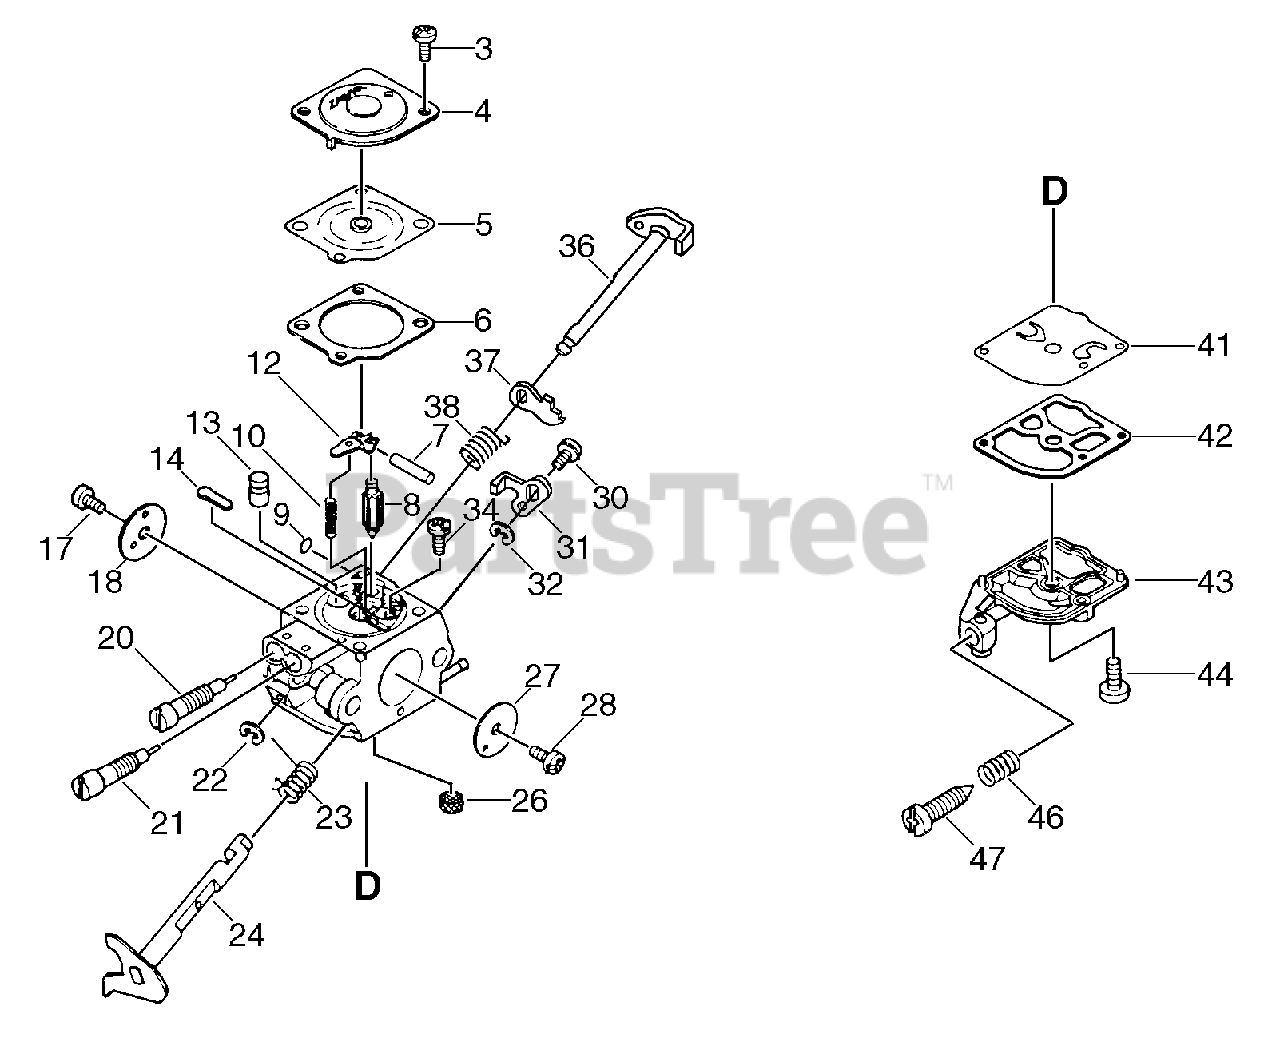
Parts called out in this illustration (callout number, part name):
4	COVER, METERING
5	DIAPHRAGM, METERING
6	GASKET, DIAPHRAGM
7	PIN, METERING LEVER
8	VALVE, INLET NEEDLE
9	PLUG, WELCH
12	LEVER, METERING
13	NOZZLE CHECK VALVE
14	PLUG, WELCH
18	VALVE, CHOKE
20	NEEDLE - HIGH SPEED
21	NEEDLE - LOW SPEED
22	RING, RETAINING
23	SPRING, THROTTLE RETURN
24	SHAFT, THROTTLE
26	STRAINER
27	VALVE, THROTTLE
31	LEVER, THROTTLE
32	RING, RETAINING
34	SCREW, METERING LEVER PIN
36	SHAFT, CHOKE
37	LEVER, CHOKE
38	SPRING, CHOKE RETURN
41	DIAPHRAGM, PUMP
42	GASKET, PUMP
43	COVER, PUMP
44	SCREW, PUMP COVER
46	SPRING, IDLE ADJUST
47	SCREW, IDLE ADJUST
